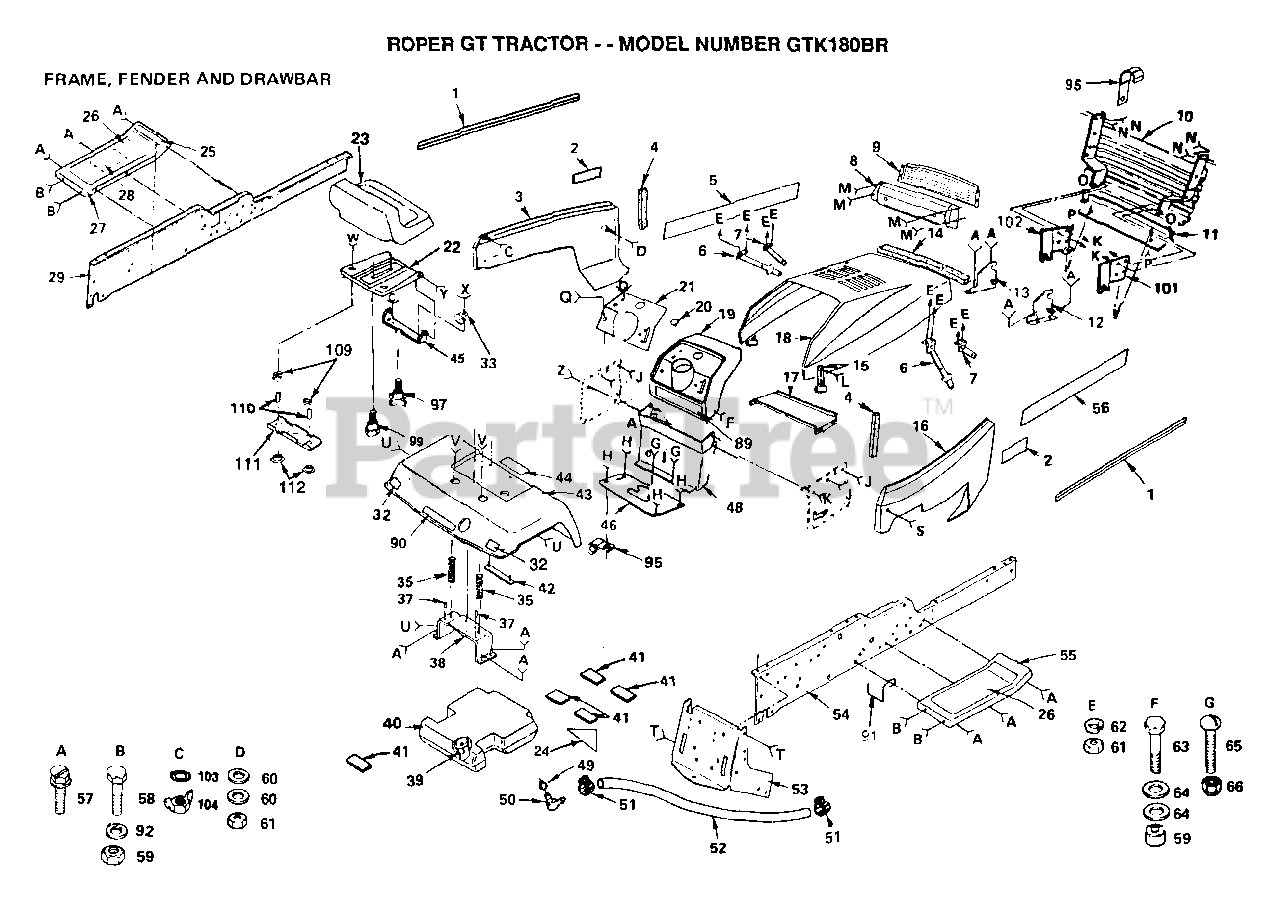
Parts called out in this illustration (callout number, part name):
4	FOAM STRIP T
9	LENS LT
12	SUPPORT RH YTH
13	SUPPORT LH YTH
15	HOOD LATCH T
20	PLUG-DASH T
25	DECAL T
27	FOOTREST LH YT
28	DECAL T
32	REFLECTOR-TAIL YT
33	CLIP T
37	NUT-PUSH YT
41	PAD-SPACER LT
44	DECAL
46	CVR SHAFT GATE
48	DASH ASSEMBLY
49	BUSHING OUTLET T
50	FUEL TANK STEM GT
57	SCREW
60	WASHER PM
63	BOLT
64	WASHER
65	SCREW
91	BELT RETAINER GT
92	WASHER
97	"KNOB 1/2"" YT"
101	SUPPORT RH YTH
102	SUPPORT LH YTH
103	LOCKWASHER GT
109	SPRING
110	SPACER SPLIT
111	BRKT SWITCH
112	BUSHING
